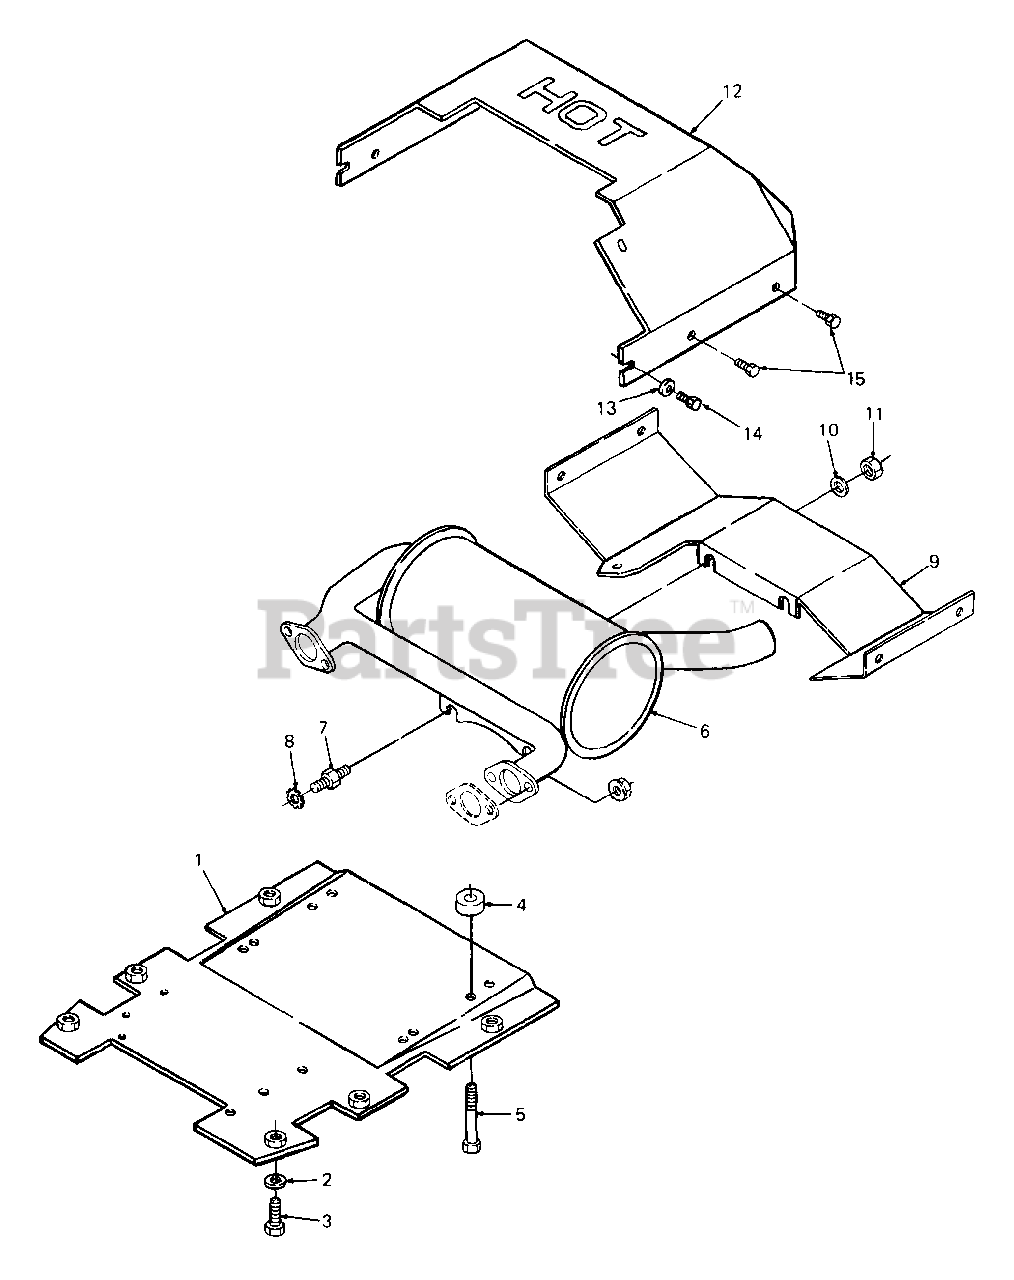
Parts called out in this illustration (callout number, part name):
3	Bolt, Patch, 3/8-16 X 1.0 Lg
4	Spacer, .423 X 1.0 X.469 Lg
5	Bolt, Patch, 3/8-16 X 2.25 Lg
7	Stud, 7/16-14 UNC-2A Thd
8	Washer, External Lock, .45 X .75 X .03 Thk
11	Nut, Hex, 7/16-14 GR5
12	Duct, Engine
13	Washer, Flat, 281 X 50 X 063 Thk
14	Bolt, Hex, M6-1 0 X 10 MM Lg GR5
15	Screw, Hex Wash Hd Tapp, #10 x .50 Lg
